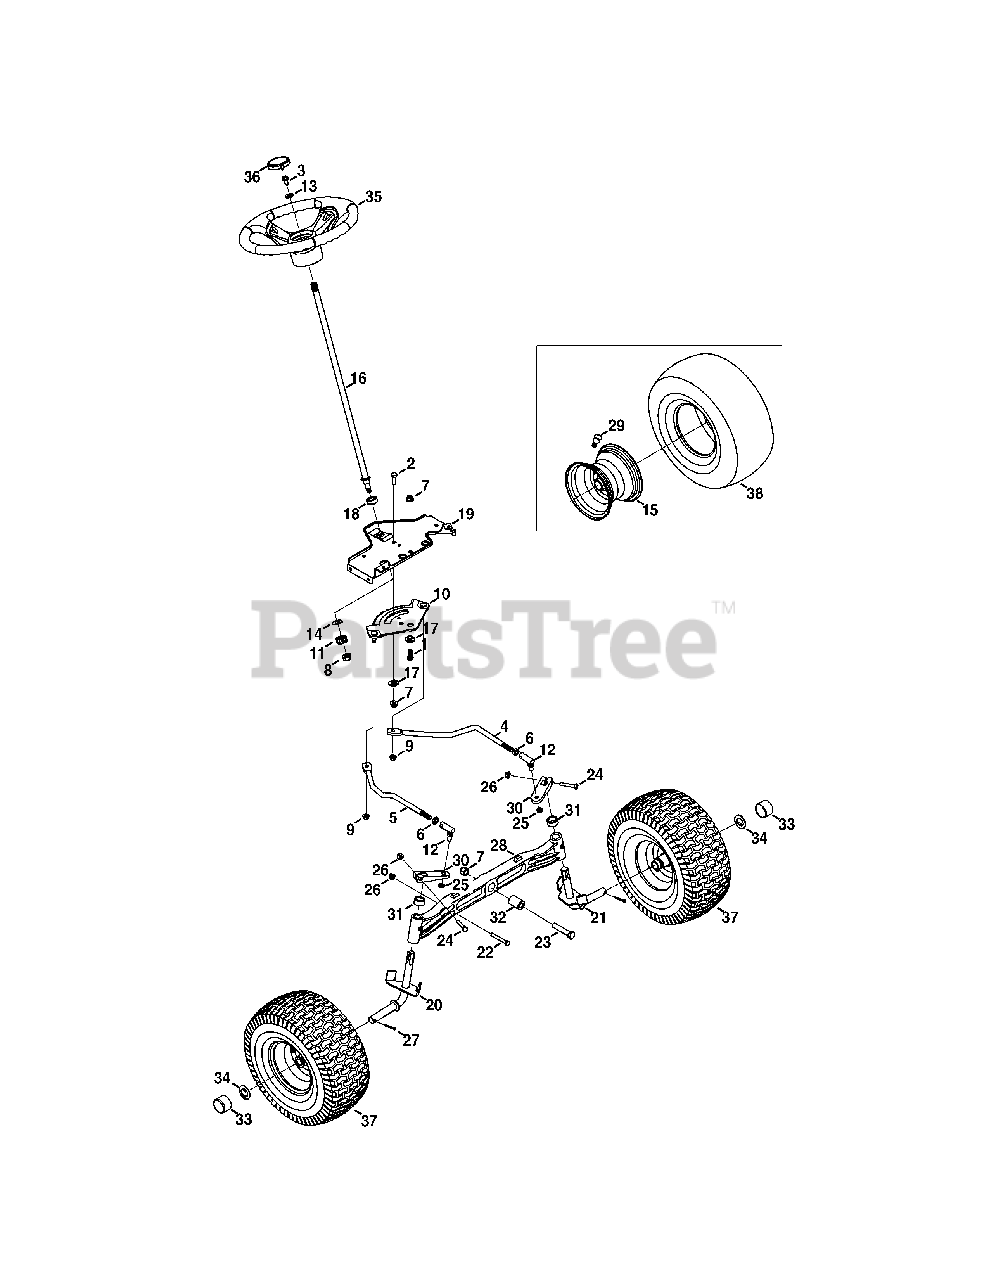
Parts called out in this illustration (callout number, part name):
1	Hex Head Screw, 3/8-16:1.00
2	Hex Head Screw, 3/8-16:1.00
3	Hex Head Screw, 5/16-18:1.00
4	LH Drag Link
5	RH Drag Link
6	Jam Nut, 7/16-20
7	Flangelock Nut, 3/8-16
8	Flangelock Nut, 7/16-20
9	Flangelock Nut, 5/16-18
10	Steering Gear
11	Steering Pinion Gear
12	Ball Joint, 7/16-20
13	Flat Washer, .406 X .875 X .105
14	Flat Washer, .51 X 1.12 X .06:HT
15	Rim Assembly
16	Steering Shaft, .625 OD X 24.25 LG
17	Shoulder Spacer, .385X 1.25 X .3025
18	Hex Flange Bearing 5/8 PM
19	Steering Support Bracket
19	Screw, .750 5/16-18
20	RH Axle Assembly
21	LH Axle Assembly
22	Hex Head Screw, 5/16-18:2.25
23	Hex Head Screw, 3/8-16:2.50
24	Hex Head Screw, 5/16-18:1.75
25	Hexlock Nut, 3/8-24
26	Flangelock Nut, 5/16-18
27	Cotter Pin, 5/32:1.25
28	Pivot Bar Axle
29	Tubeless Air Valve
30	Steering Block
31	Spacer, .71 ID X .125 OD X .56LG
32	Spacer, .385 X 1.00 X 1.5075
33	Bumper Cap
34	Flat Washer, .781ID x 1.590OD
35	Steering Wheel
36	Steering Wheel Cap
37	Wheel Assembly
